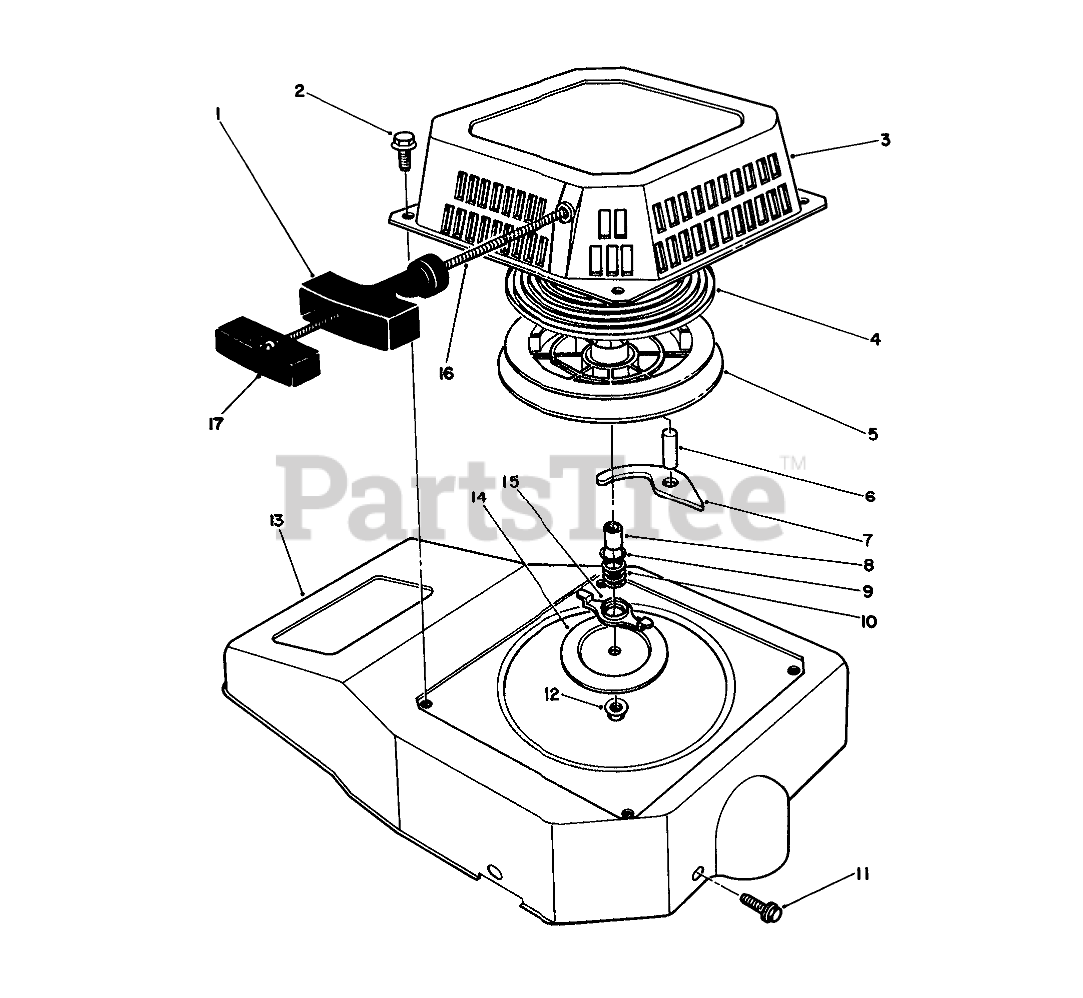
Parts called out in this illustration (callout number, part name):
1	HANDLE
2	SCREW-HHF
3	Case-Recoil
4	SPRING
8	Spacer
9	WASHER
10	Spring-Friction
13	SHROUD
14	PLATE
15	Guide-Paw
16	ROPE-STARTER
17	RETAINER HANDLE
